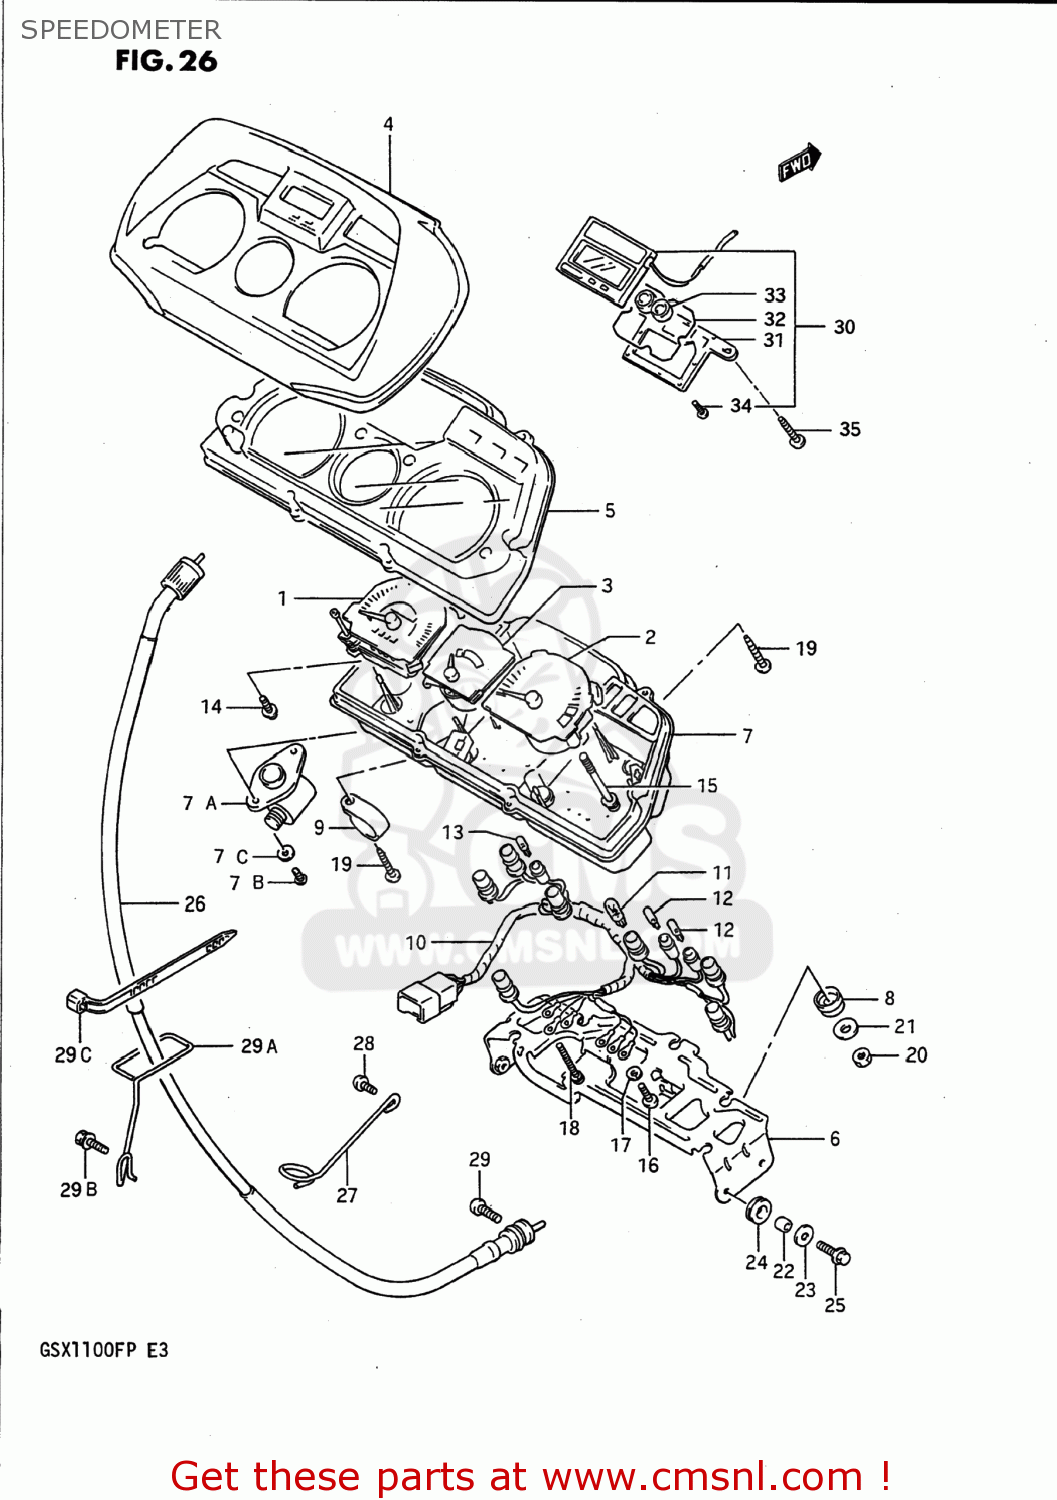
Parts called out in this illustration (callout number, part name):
1	SPEEDOMETER
2	TACHOMETER
3	METER,FUEL
4	VISOR
5	GLASS ASSEMBLY
6	BRACKET,METER
7	CASE
7A	GEAR BOX
7B	SCREW
7C	WASHER (4X16X1.2)
8	CUSHION
9	CLAMP,METER
10	SOCKET,METER
11	BULB(12V3.4W,T10)
12	BULB(12V3W,T6.5)
13	BULB(12V1.7W,T6.5)
14	SCREW
15	SCREW (4X36)
16	SCREW
17	LOCK WASHER
18	SCREW(3X22)
19	SCREW
20	NUT 5MM
21	WASHER (5.5X16X1.2)
22	SPACER (6.3X9.1X6.7)
23	WASHER
24	CUSHION
25	BOLT 6X20
26	CABLE ASSY,SPEEDOMETER
27	CLAMP,SPEEDOMETER CABLE
28	BOLT
29	SCREW
29A	GUIDE,SPEEDOMETER CABLE
29B	BOLT
29C	CLAMP(L:125)
30	CLOCK ASSEMBLY
31	CASE,LOWER
32	GASKET (NAS)
33	BATTERY,LITHIUM
34	SCREW,TAPPING
35	SCREW(3X16)
